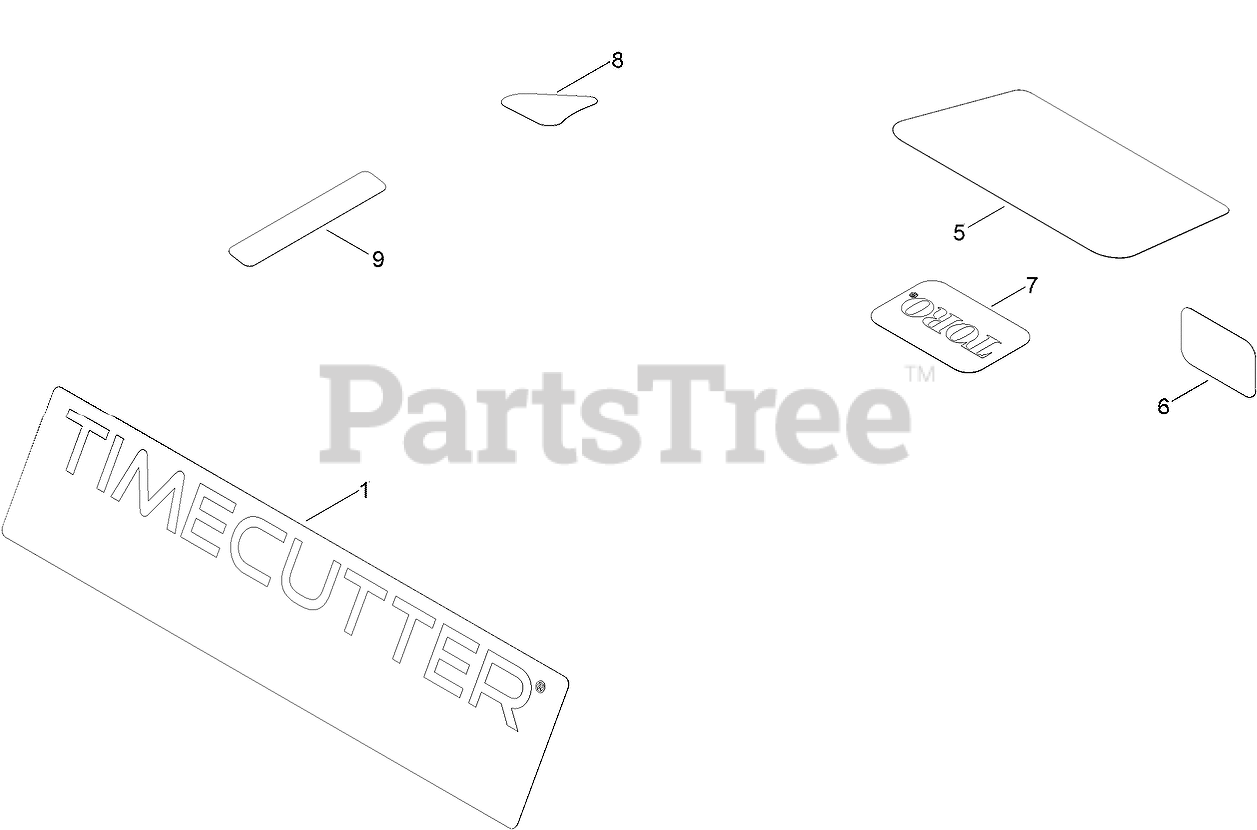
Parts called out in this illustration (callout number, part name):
1	DECAL-TIMECUTTER
5	DECAL-ENGINE
6	PLACARD-INTAKE
8	DECAL-DRAIN, OIL
9	DECAL-SHUTDOWN
